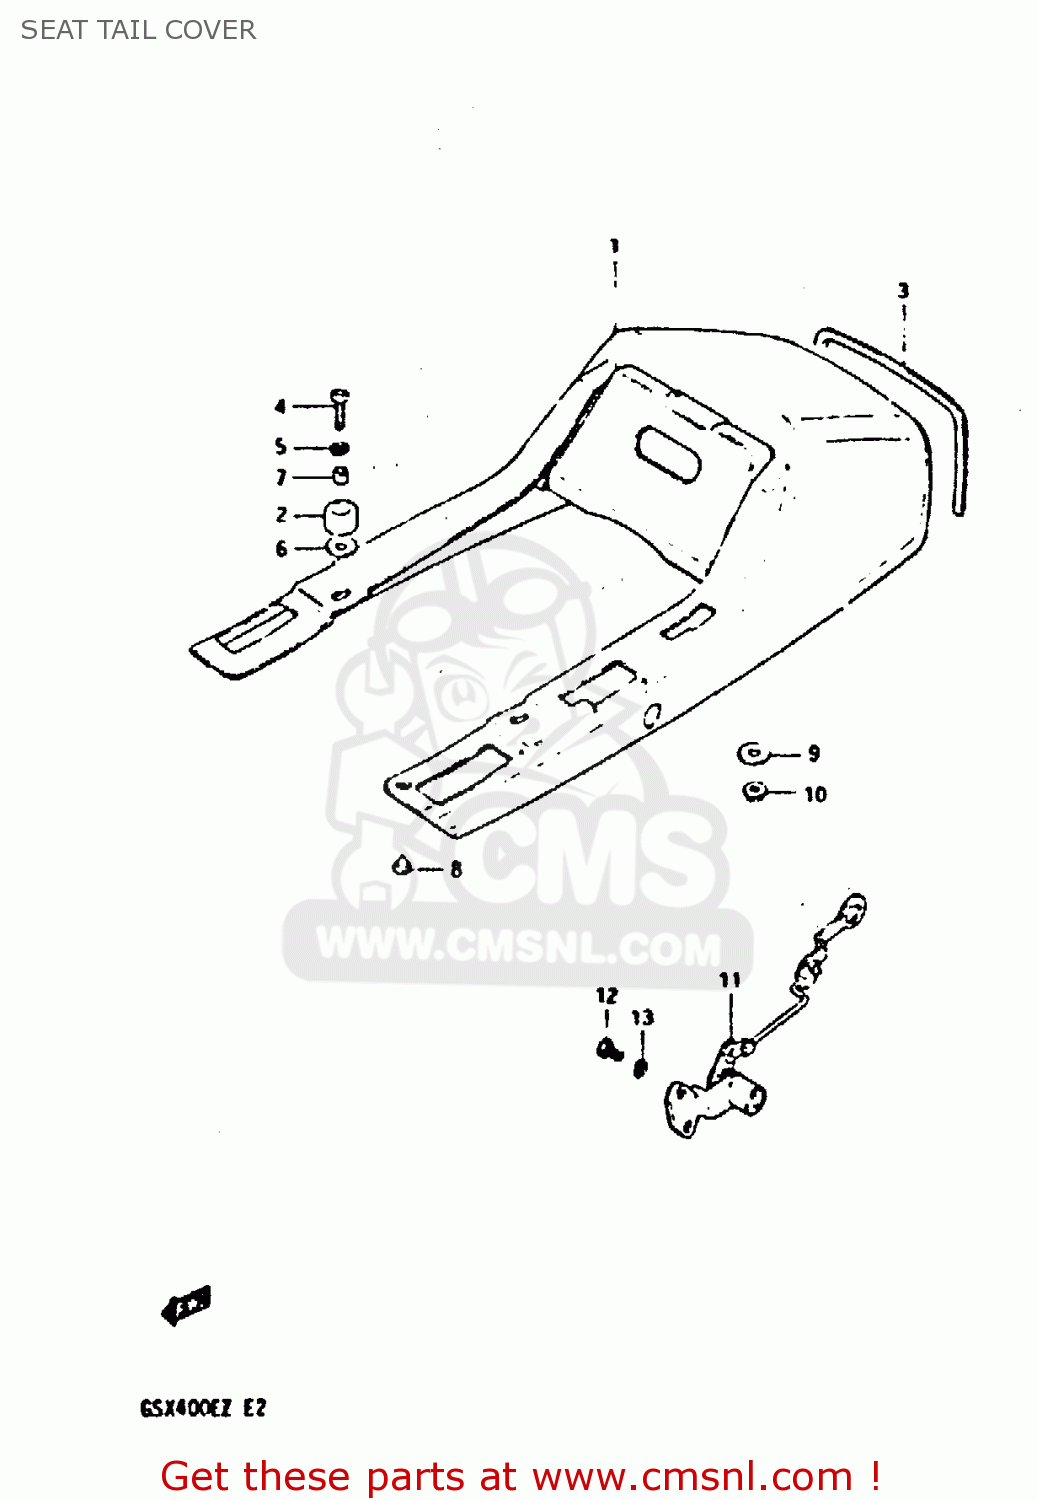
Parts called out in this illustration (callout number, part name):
1	TAIL COVER, SEAT (RED)
2	CUSHION,COVER
3	CUSHION,TAIL SEAT COVER
4	SCREW
5	LOCK WASHER
6	WASHER (6.5X24X1.6)
7	SPACER
8	CUSHION
9	WASHER
10	NUT 6MM
11	LOCK ASSEMBLY,SEAT
12	BOLT
13	LOCK WASHER
